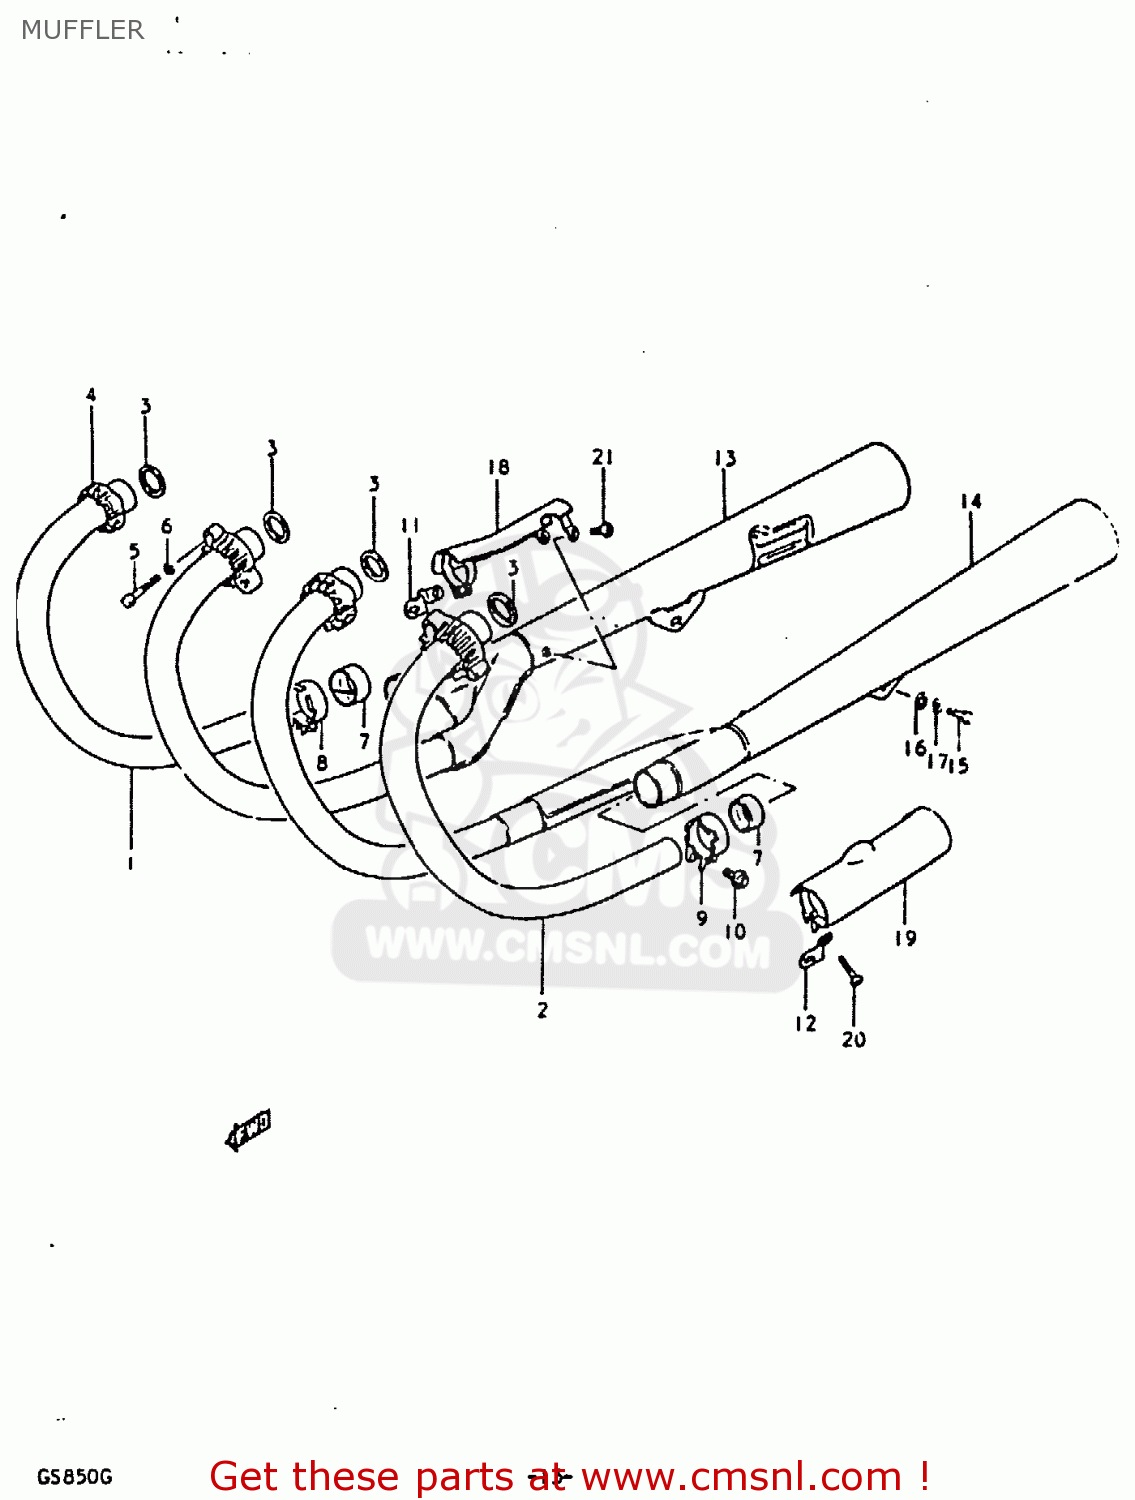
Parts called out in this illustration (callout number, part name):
1	PIPE,EXHAUST,RIGHT
2	PIPE,EXHAUST,LEFT
3	GASKET,EXHAUST PIPE (NAS)
4	CLAMP,EXHAUST PIPE
5	BOLT
6	LOCK WASHER
7	CONNECTOR,MUFFLER
8	CLAMP
9	CLAMP
10	BOLT
11	PLATE, CONNECTOR RH
12	PLATE, CONNECTOR LH
13	BODY,MUFFLER
14	BODY,MUFFLER
15	BOLT 10X30
16	WASHER
17	LOCK WASHER
18	COVER,MUFFLER
19	COVER,MUFFLER
20	SCREW
21	SCREW
